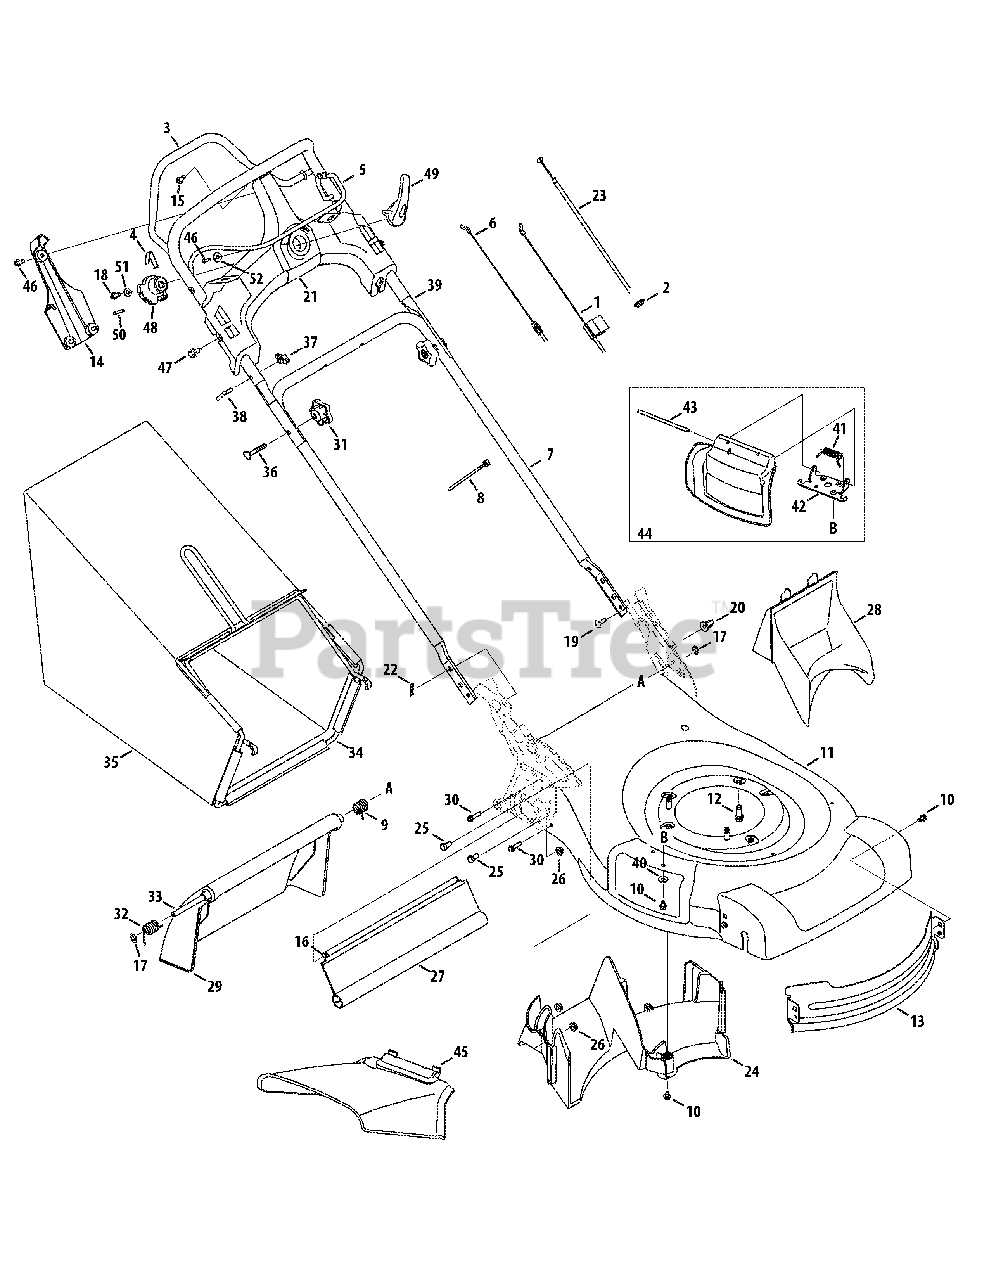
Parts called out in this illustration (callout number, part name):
1	Control Cable
2	Rubber Grommet
3	Drive Control
4	Shift Spring
5	Blade Control
6	Drive Cable
8	Cable Tie
9	Torsion Spring, LH
10	TT Screw, 1/4-20 x .500
12	TT Screw, 3/8-16 x 1.00
13	Front Deck Baffle
14	Variable Spd. Cont. Panel Cover
15	Screw, TT, 1/4-20 x .750
16	Screw, #10-16 x .500
17	Nut, Speed
18	Screw, 1/4-15 x .750
19	Carriage Bolt, 1/4-20
20	Wing Nut
21	Variable Speed Control Panel
22	Cotter Pin
23	Variable Speed Cable
24	Rear Baffle
25	Screw, 5/16-18 x .625
26	Flange Lock Nut, 5/16-18
27	Trail shield
28	Mulch Plug
30	Screw, 1/4-15 x 1.00
32	Torsion Spring, RH
34	Grass Catcher Frame
35	Grass Catcher
36	Carriage Bolt, 5/16-18 x 2.00
40	Bell Washer, .265 x .75 x .062
41	Torsion Spring
42	Chute Deflector Adapter
43	Hinge Pin
44	Mulch Plug Assembly
45	Side Discharge Chute
46	Screw, #12-16 x .75
47	Screw, AB, 1/4-14 x .625
48	4 Speed Actuator
49	Speed Selector Level
51	Washer, Flat, .344 x .688 x .065
52	Washer, Flat, .250 x .750 x .119
